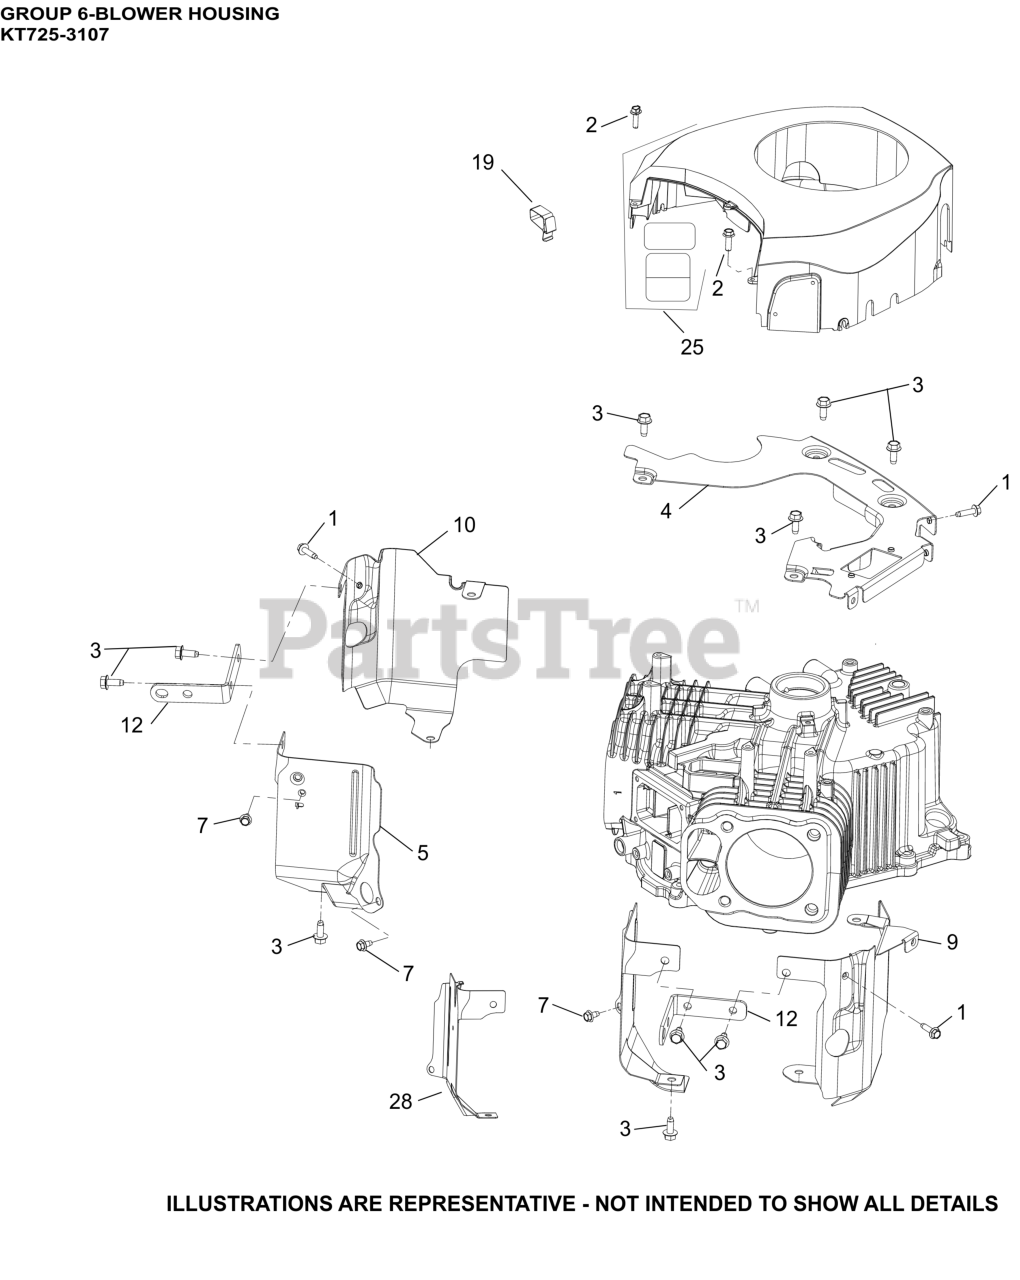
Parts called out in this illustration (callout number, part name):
1	SCREW, THD FRM-USE 25 086 473-S
2	SCREW, HI-LOW
3	SCREW, THREAD FORMING
4	PLATE, BACKING
5	BAFFLE, VALLEY #1
7	SCREW, THREAD FORMING
9	BAFFLE, LEFT BARREL
10	BAFFLE, RIGHT BARREL
12	STRAP, LIFTING
19	CLIP, BLOWER HOUSING
25	KIT, BLOWER HOUSING
28	BAFFLE, VALLEY #2
